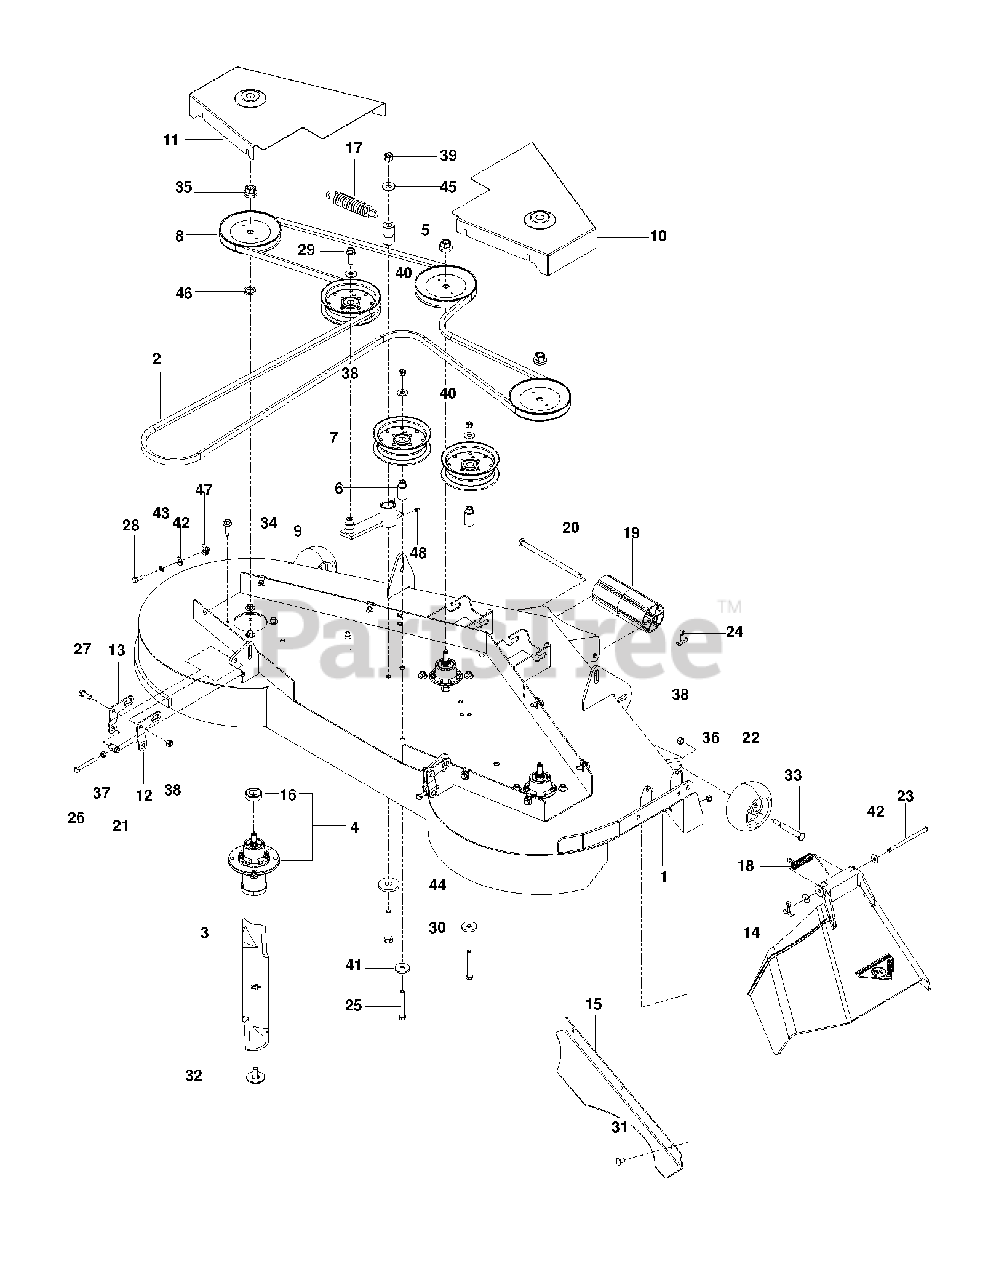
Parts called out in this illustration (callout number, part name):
1	DECK MZT 61 W/SFTY DECALS ORG
2	BELT, DECK
3	BLADE, 21"
4	MANDREL ASM, CAST IRON
5	PIVOT BUSHING
6	IDLER BUSHING
7	PULLEY, IDLER
10	BELT SHIELD, RH ORANGE
11	BELT.SHIELD.LH.ORANGE
12	PITCH, ADJUST, RT
13	PITCH, ADJUST, LT
14	DISCHARGE CHUTE 61"
15	CONFINEMENT PLATE 61
16	BEARING, BALL
18	SPRING - TORSION
19	NOSE ROLLER 48"
20	ROD.ROLLER.NOSE.NARROW.48"
21	TRUNION, PITCH
22	GAUGE WHEEL
23	PIN-CLEVIS 5/16 DIA X 5.19 ZD
24	RP_COTTER PIN 1/8 X 3/4
25	HCS 3/8C X 3
26	HCS 5/16-18 X 2 1/2 TPBLT
27	HCS 3/8-16X1.GRD.5.ZD
28	HCS 5/16C X 3/4
29	4CS 3/8C X 1 SERRATED HEAD
30	HCS 1/2C X 3 1/4
31	CARRIAGE BOLT 5/16C X 5/8"
32	BOLT.WASHER.ASM.7/16-2
33	SHOULDER BOLT 1/2X2-5/8 ZD SPE
34	WASHER HEAD SCREW
35	LOCKNUT - 9/16
36	NUT 5/16 NYLOC
37	NUT 5/16C HEX
38	NUT 3/8-16 NYLOC
39	RP NUT 1/2-13 HEX NYLOC ZD
40	RP WASHER 3/8 FLAT
41	SPINDLE WASHER
42	WASHER 5/16 FLAT
43	WASH 5/16 DISC SPRING ZD
44	WASHER, SUPPORT
45	WASHER 1/2 FLAT
46	WASHER-SPACER
47	U-CLIP 5/16-18 NUT RETAINER
48	ZERK
